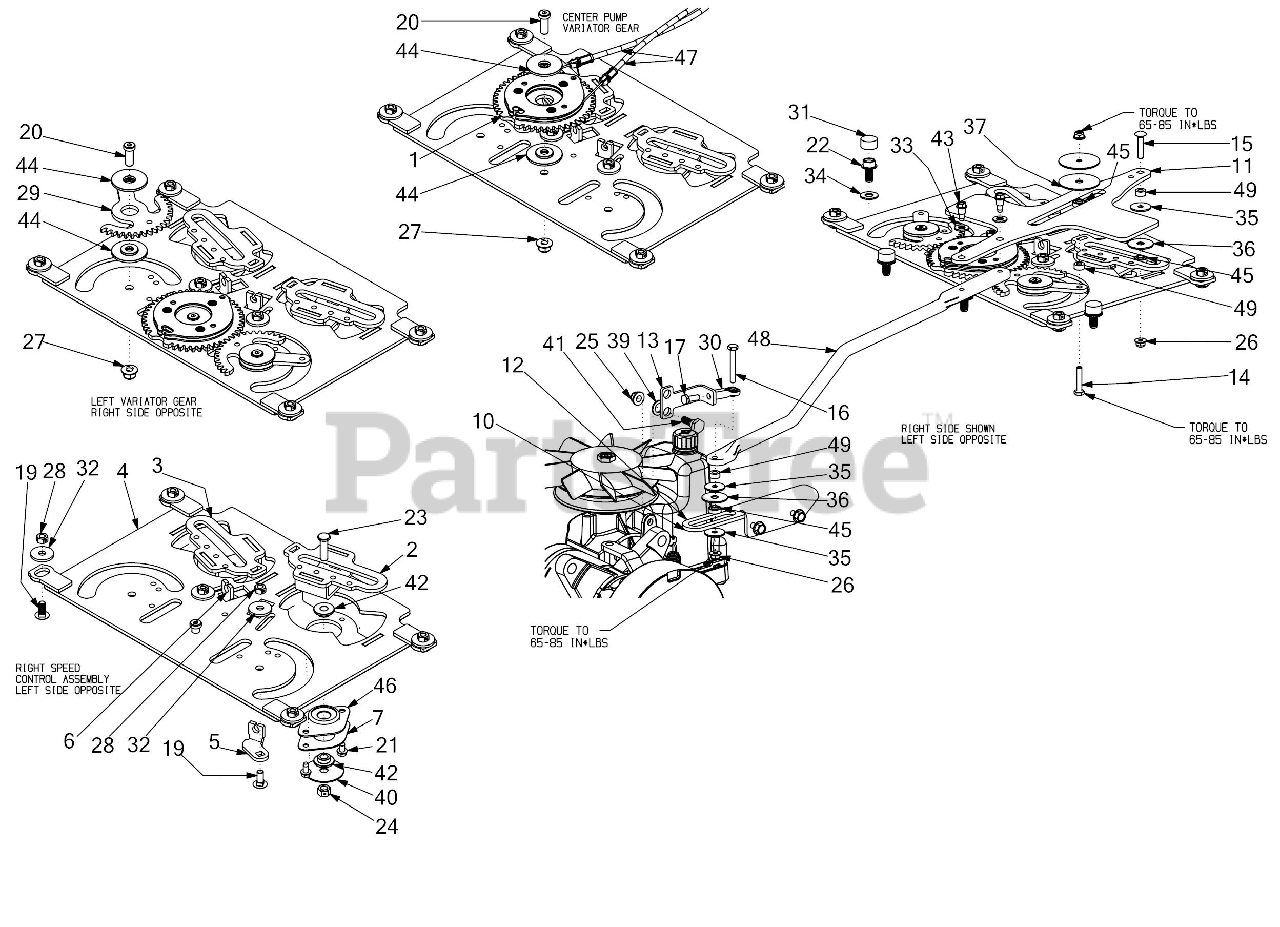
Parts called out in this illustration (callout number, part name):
1	PUMP GEAR
2	PUMP CONTROL CAM ASSEMBLY (RH)
3	PUMP CONTROL CAM ASSEMBLY (LH)
4	PUMP CONTROL MOUNTING PLATE
5	STEERING CABLE BRACKET
6	CABLE CLAMP BRACKET
7	RETAINING PLATE
10	PUMP ARM GUIDE BRACKET (RH)
11	STEERING PUMP ACTUATOR ARM
12	PUMP ARM GUIDE BRACKET (LH)
13	PUMP CONTROL BRACKET
14	HEX SCREW 1/4-20 x 1.25
15	CARRIAGE BOLT 1/4-20 x 1.25 Gr5
16	HEX SCREW 1/4-20 x 1.75
17	HEX SCREW 1/4-28 x .75
19	CARRIAGE BOLT 5/16-18 x .75
20	SCREW 3/8-16 x 1
21	SCREW 1/4-20 X.500
22	SCREW 3/8-16 x 3/4
23	SCREW 3/8-16 x 1.25 GR5
25	FLANGE LOCK NUT 5/16-18
26	FLANGE LOCK NUT
28	HEX NUT
29	STEERING GEAR YOKE
30	END ROD (RH)
31	SLIDE CAP
32	FLAT WASHER
33	FLAT WASHER
34	FLAT WASHER
35	FLAT WASHER
36	WASHER .355X1.25X.06THK
37	FLAT WASHER
39	FLAT WASHER .469X.750X.054
40	HUB CAP WASHER .406 x 1.92 x .060
41	SHOULDER SCREW .437
42	SHOULDER SPACER
43	SHOULDER SCREW
44	SHOULDER SPACER
45	BALL BEARING .25 x .625 SPCL
46	BALL BEARING
47	TRANSMISSION CONTROL LINK CABLE
48	PUMP CONTROL ROD
